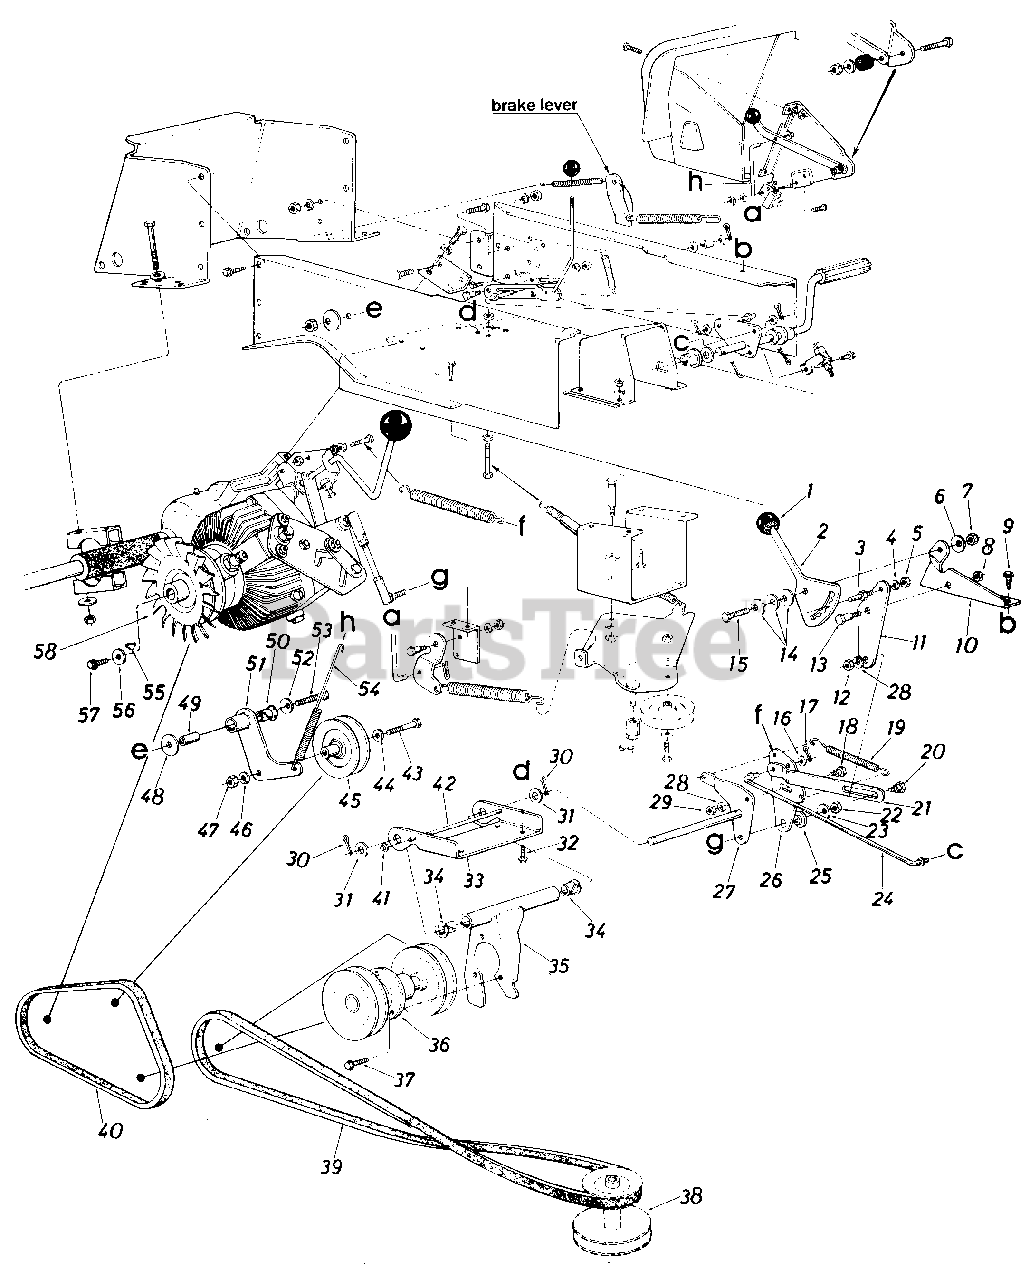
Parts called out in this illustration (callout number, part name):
1	Gear Shift Knob
2	Speed Selector Cam
3	Hex Stud .250" Dia. x .62"
4	L-Wash. 1/4" I.D.*
5	Hex Nut 1/4-20 Thd.*
6	Bell-Wash. .400" I.D. x 1.13" O.D.
7	Hex Ins. L-Nut 3/8-24 Thd.
8	Hex Top L-Nut 3/8-16 Thd.
9	Hex Wash. Hd. S-Tap Scr. 1/4-20 x .75" Lg.
10	Speed Selector Mtg. Brkt
11	Speed Selector Transfer Brkt
12	Hex Nut 5/16-18 Thd."*
13	Shld. Bolt .500" Dia. x .170
14	Bell-Wash. .39" I.D. x 1.13" O.D.
15	Hex Bolt 3/8-24 x 1.00" Lg.*
16	Fl-Wash. .385" I.D. x .87" O.D.
17	Cotter Pin 3/32" Dia. x .75" Lg.*
18	Shld. Bolt .437" Dia. x .180
19	Extension Spring .50" Dia. x 2.75" Lg.
20	Shld. Bolt .437" Dia. x .180
21	Speed Selector Link
22	Hex Top L-Nut 3/8-24 Thd.
23	Bell-Wash. .39" I.D. x 1.13" O.D.
24	Rod Speed Control .312" Dia.
25	Shld. Spacer .625" I.D.
26	Speed Cont. Transfer Swivel Brkt
27	Speed Control Transfer Ass'y
28	L-Wash. 5/16" I.D.*
29	Hex Nut 5/16-18 Thd.*
30	Cotter Pin 1/8" Dia. x 1.00" Lg.*
31	Fl-Wash. .69" I.D. x 1.24" O.D.
32	Hex Wash S-Tap Scr. 1/4-20 x .50" Lg.
33	Idler Mtg. Brkt.
34	Flanged Nyliner Brg. .376 I.D. x .437
35	Mounting Brkt. Ass'y
36	Jack Shaft Ass'y.
37	Hex Sems Bolt 5/16-18 x .75" Lg.*
38	Engine Pulley 47.5" I.D. x 5.56" O.D.
39	V-Belt 1/2" x 59.0" Lg.
40	V-Belt 1/2 " x 32.0 " Lg.
41	Push Cap
42	Rod 3/16" Dia. x 7.12" Lg.
43	Hex Bolt 3/8-24 x 1.50" Lg.
44	Fl-Wash. .385" I.D. x .87" O.D.
45	Idler Pulley 4.0" O.D. x 5/8"-"V"
46	L-Wash. 3/8" I.D.
47	Hex Nut 3/8-24 Thd.
48	Bell-Wash. .40" I.D. x .87" O.D.
49	Spacer.38" I.D. x .62" O.D. x 1.87" Lg.
50	Flanged Nyliner Brg.
51	Idler Pivot Brkt. Ass'y
52	Fl-Wash. .385" I.D. x .87" O.D.
53	Hex Bolt 3/8-24 x 2.00" Lg.
54	Extension Spring .56" O.D. x 7.75" Lg.
55	#9 Hi-Pro Key .316" x .75" Dia.
56	Fl-Wash. .25" I.D. x .938" O.D.
57	Hex Wash. Hd. TT-Tap Scr. 1/4 x .75" Lg.
58	Trans. Pulley and Fan Ass'y.
